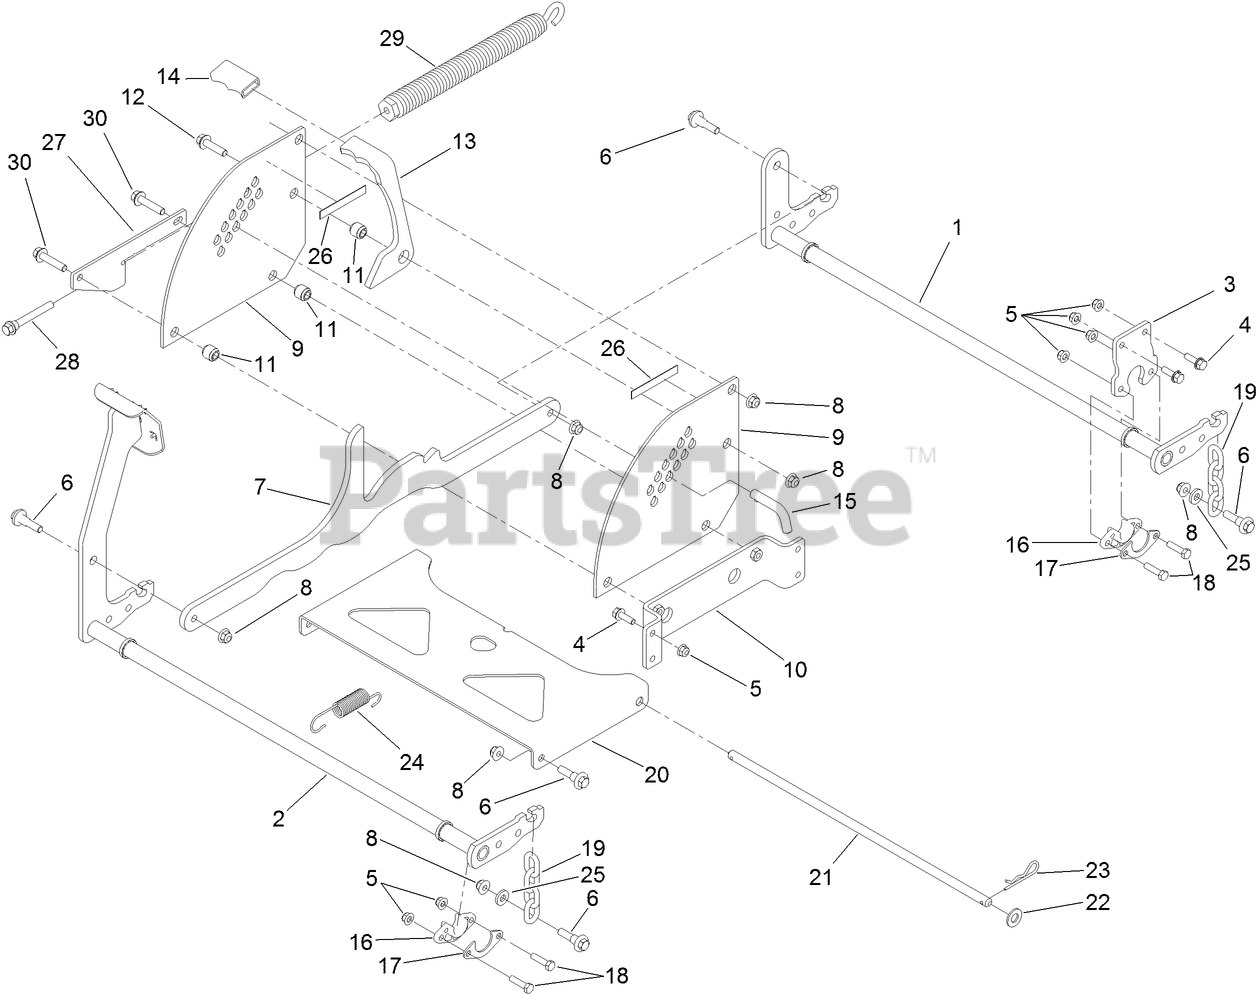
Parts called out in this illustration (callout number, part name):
1	PIVOT-REAR
2	PIVOT-FRONT
4	SCREW-HHF
5	NUT-HF, NI
6	BOLT-SHOULDER
7	LINK-HOC
8	NUT-HF, NI
9	PLATE-DECK, LIFT
10	PLATE-LIFT
11	SPACER-STEP, DOUBLE
12	SCREW-HHF
13	LOCK-TRANSPORT, HOC
14	GRIP-FLAT
15	PIN-HOC
16	BUSHING-FLANGE
17	GUSSET-LIFT, DECK
18	SCREW-HH
19	CHAIN-DECKLIFT
20	PAN-PIVOT, DECK
21	ROD-PIVOT, DECK
22	WASHER-FLAT
23	PIN-COTTER
24	SPRING-EXTENSION
25	SPACER
26	PAD-RUBBER
27	SUPPORT-SPRING
28	BOLT-SHOULDER
29	SPRING-EXTENSION
30	SCREW-HHF
